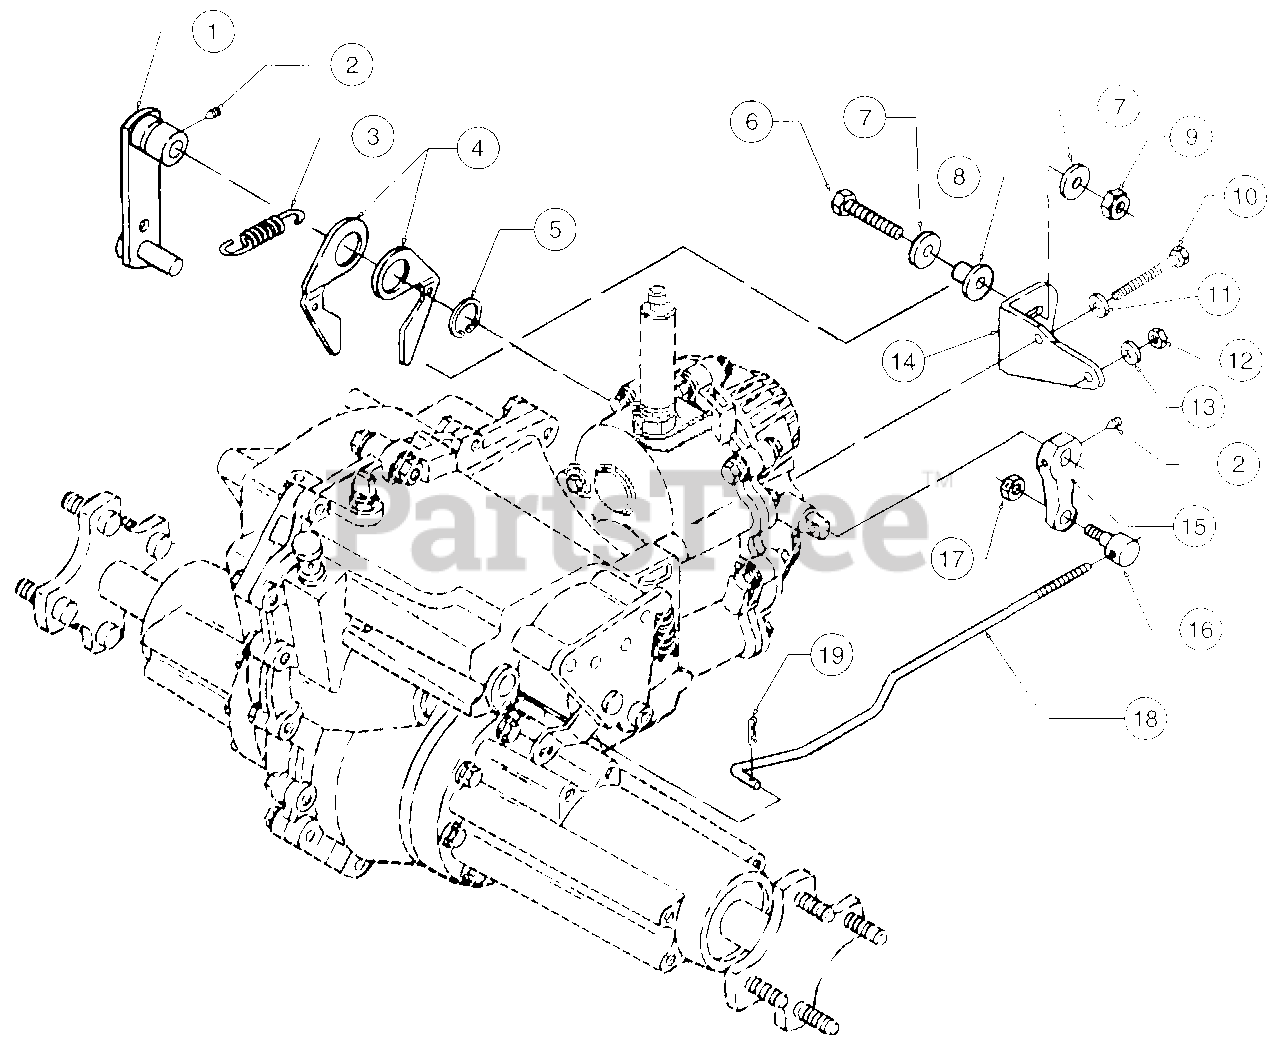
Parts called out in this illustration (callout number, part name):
1	Arm Assy, Control
2	Screw w/Patch, Set
3	Spring, Extension, .477 OD x 1.68 Lg
4	Arm, Neutral
5	Ring, Snap, .875 Shaft
6	Screw, Hex Cap, 1/4-20 x 1.25
7	Washer, Flat, .25 x .93 x .120
8	Spacer, Centering
9	Nut, Hex Top Lock, 1/4-20
10	Screw, Hex Cap, 5/16-18 x 4.0
11	Washer, Lock, 5/16
12	Nut, Hex Center Lock, 1/4-20
13	Washer, Flat, .25 x .62 x .052
14	Bracket, 6-Speed Neutral
15	Arm, Clutch/Brake
16	Ferrule, 5/16-24 Thrd
17	Nut, Hex Center Lock Jam, 5/16-24
18	Rod, Shift Interlock
19	Pin, Internal Cotter
